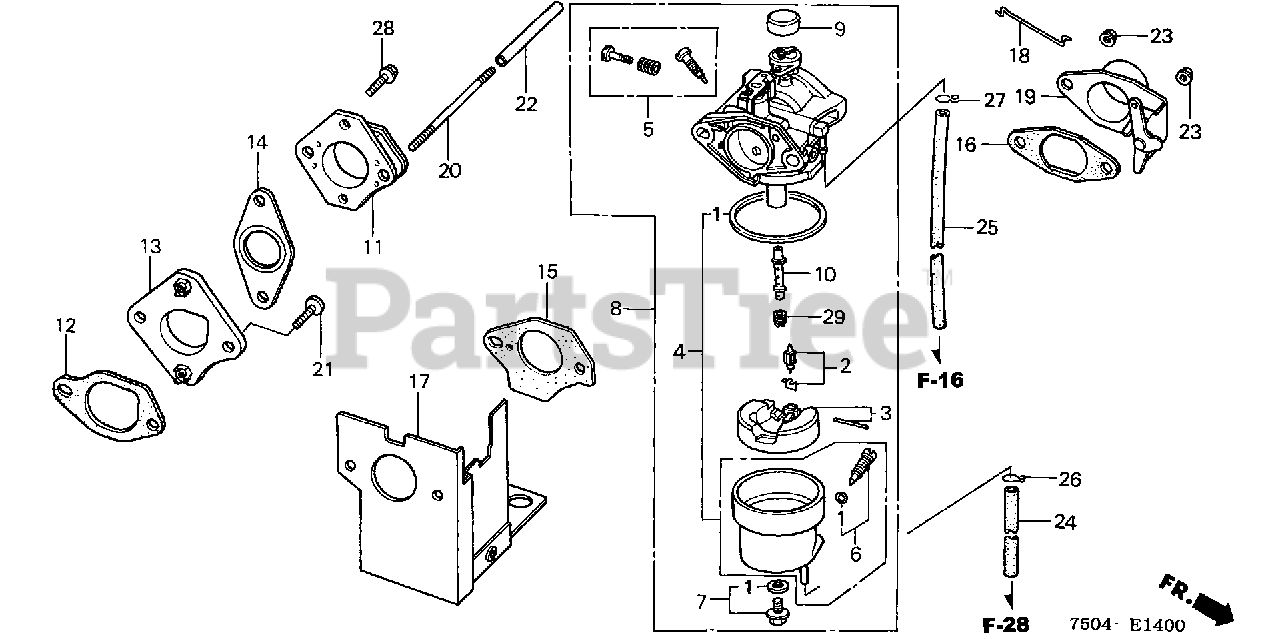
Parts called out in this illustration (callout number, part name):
1	GASKET SET (NOT AVAILABLE)
2	VALVE SET, FLOAT
4	CHAMBER SET, FLOAT
5	SCREW SET A
6	SCREW SET, DRAIN
7	SCREW SET B
8	CARBURETOR ASSY.
9	CAP, CHOKE LEVER DUST
10	NOZZLE, MAIN
11	INSULATOR, CARBURETOR
12	GASKET, INSULATOR
13	PLATE, INSULATOR
14	GASKET, INSULATOR PLATE
15	GASKET, CARBURETOR
16	GASKET, AIR CLEANER
17	COVER, CARBURETOR
18	ROD, CHOKE (NOT AVAILABLE)
19	STAY ASSY., CHOKE CONTROL (NOT AVAILABLE)
20	BOLT, STUD (6X85)
21	SCREW (8X20)
23	NUT, FLANGE (6MM)
24	BULK HOSE, FUEL (3.5X3000) (3.5X250)
25	BULK HOSE, FUEL (4.5X3000) (4.5X320)
26	CLIP, TUBE (B7)
27	CLIP, TUBE (B8)
28	BOLT, FLANGE (6X16)
29	JET, MAIN (#95)
29	JET, MAIN (#98)
29	JET, MAIN (#100)
